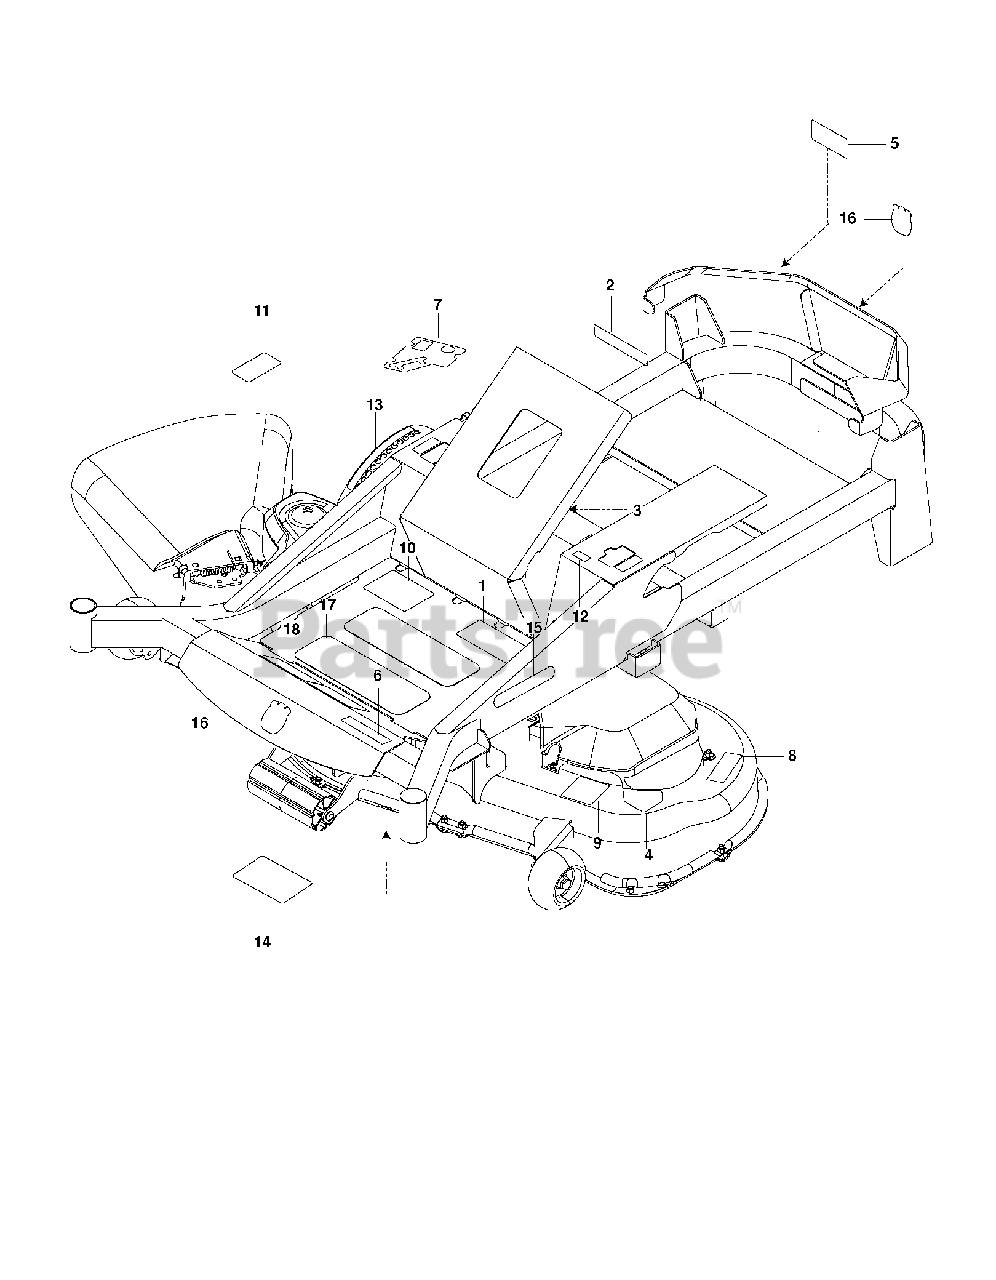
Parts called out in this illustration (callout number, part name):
1	DECAL, WARNING
2	EURO DECAL-BATTERY WARNIN6
3	DECAL, MOTION CONTROL
4	DECAL, DECK DEFLECTOR, WARNING
5	DECAL, BELT DRIVE
6	DECAL.MZ.54S.E
7	DECAL, CONSOLE HUS
8	DECAL, EURO SEVERING
9	DECAL, BELT ROUTING
10	DECAL.ZTR.STRTNGINST.REMOTECHK
11	DECAL.DECK.6MIL./DEF.SHLD.WARN
12	DECAL, F.S.T.
13	DECAL, HEIGHT ADJUST
14	DECAL, SERVICE
15	RP.DECAL.BADGE.170MM.TEXTLOGO
16	DECAL.AUGER.HUSQ.CROWN.SNOW
17	ANTI-SKID PAD
